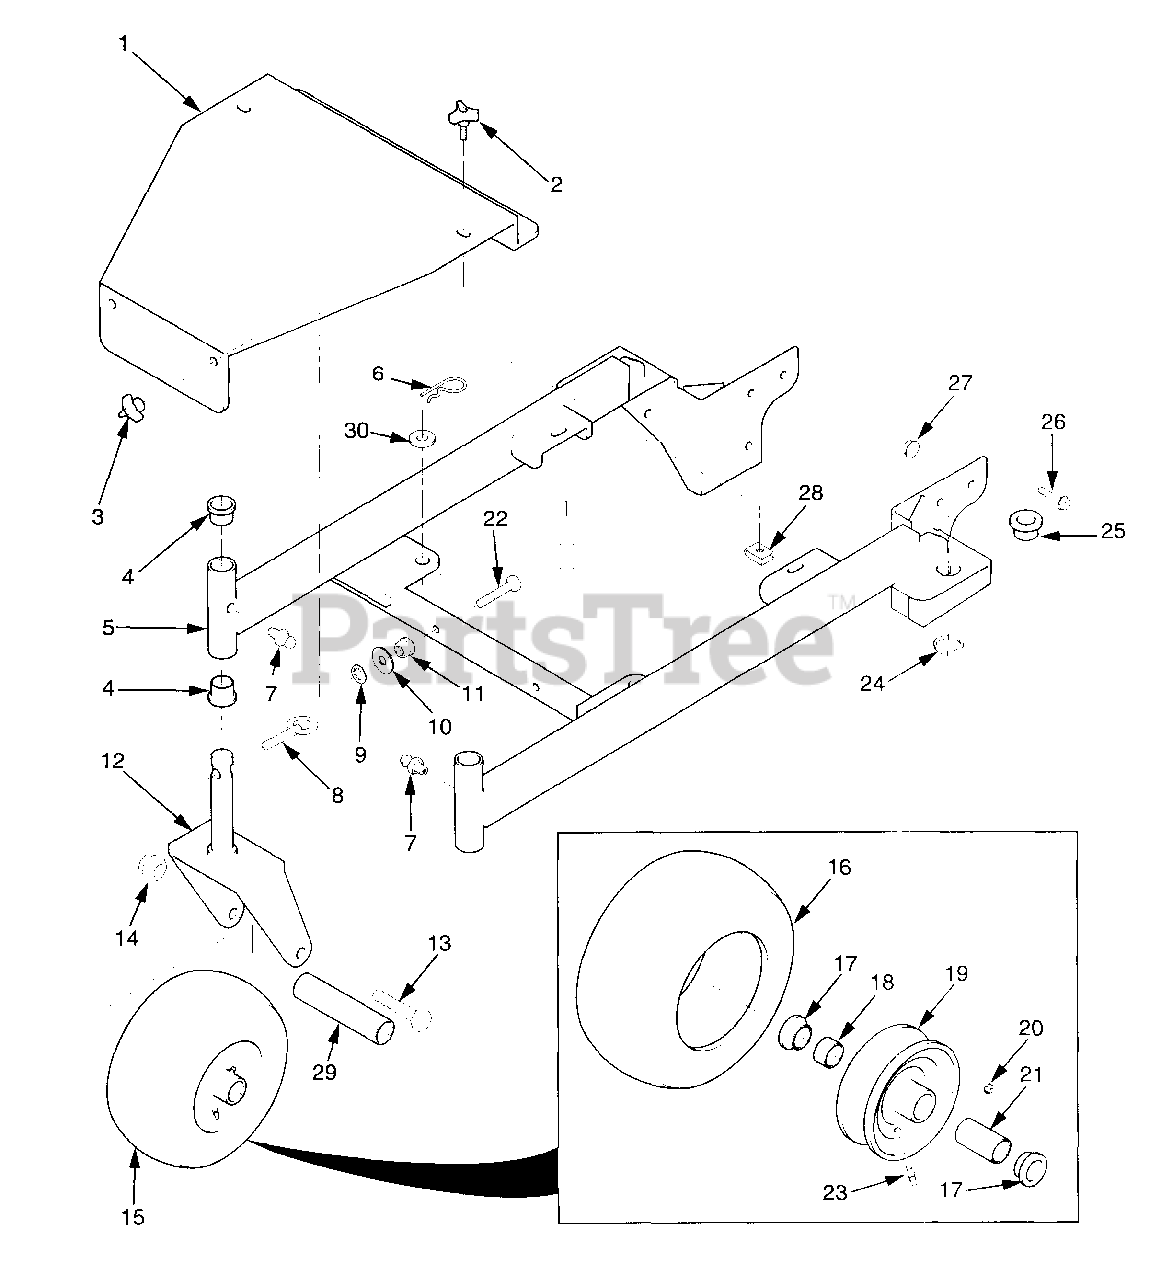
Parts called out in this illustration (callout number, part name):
1	Belt Cover With Decal
2	Knob With Stud
3	Knob, Deck Cover Mounting
4	Bushing, Caster
5	Frame Weldment, Deck Mounting - 36"
6	Hair Pin Cotter, .177 x 3.25"
7	Grease Fitting Str. 1/4-28 Self Tap
8	Quick Pin, .438 Dia
9	Nut, Push-On - 3/8 Thd.
10	Flatwasher, 3/8 - (.391 x .938 x .105)
11	Nut, 3/8-16 Serrated Flange Hex Head
12	Yoke, Caster Wheel
13	Capscrew, Hex Head 1/2-13 x 6.50"
14	Locknut, 1/2-13 Elastic Stop
15	Wheel Assembly, Caster
16	Tire, 11 x 4.00-5
17	Retainer
18	Roller Bearing
19	Rim, 5.0 x 2.75 With Zerk & Valve
20	Grease Fitting Str. 1/4-28
21	Roller Bearing .625 x 3.25"
22	Capscrew, Hex Head 3/8-16 x 2.25"
23	Tire Valve
24	Retaining Ring 1.50 Ext.
25	Bushing, Deck Adjustment Pin
26	Capscrew, Hex Head 7/16-14 x 1.0"
27	Nut, 7/16-14 Serrated Flange Hex
28	U-Nut, 3/8-16
29	Sleeve, Caster Wheel
30	Flatwasher, 5/8 - (..688 x 1.75 x .134)
